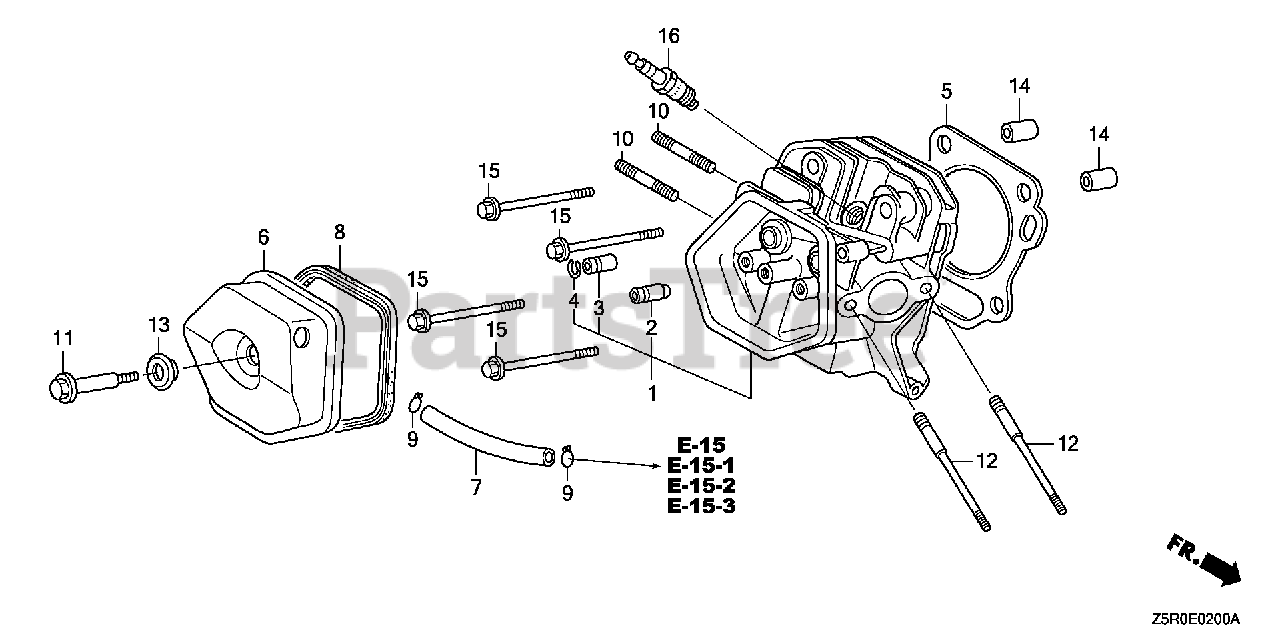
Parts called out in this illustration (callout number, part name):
1	CYLINDER HEAD
2	GUIDE, VALVE (OVER SIZE)
3	GUIDE, EX. VALVE (OVER SIZE)
4	CLIP, VALVE GUIDE
5	GASKET, CYLINDER HEAD
6	COVER, HEAD
7	TUBE, BREATHER
8	GASKET, HEAD COVER
10	BOLT, STUD (8X22)
11	BOLT, HEAD COVER
12	BOLT, STUD (8X106)
13	WASHER, HEAD COVER
14	PIN, DOWEL (12X20)
15	BOLT, FLANGE (10X80)
16	SPARK PLUG (BPR5ES) (NGK)
16	SPARK PLUG (W16EPR-U) (DENSO)
16	SPARK PLUG (BPR6ES) (NGK)
16	SPARK PLUG (W20EPR-U) (DENSO)
